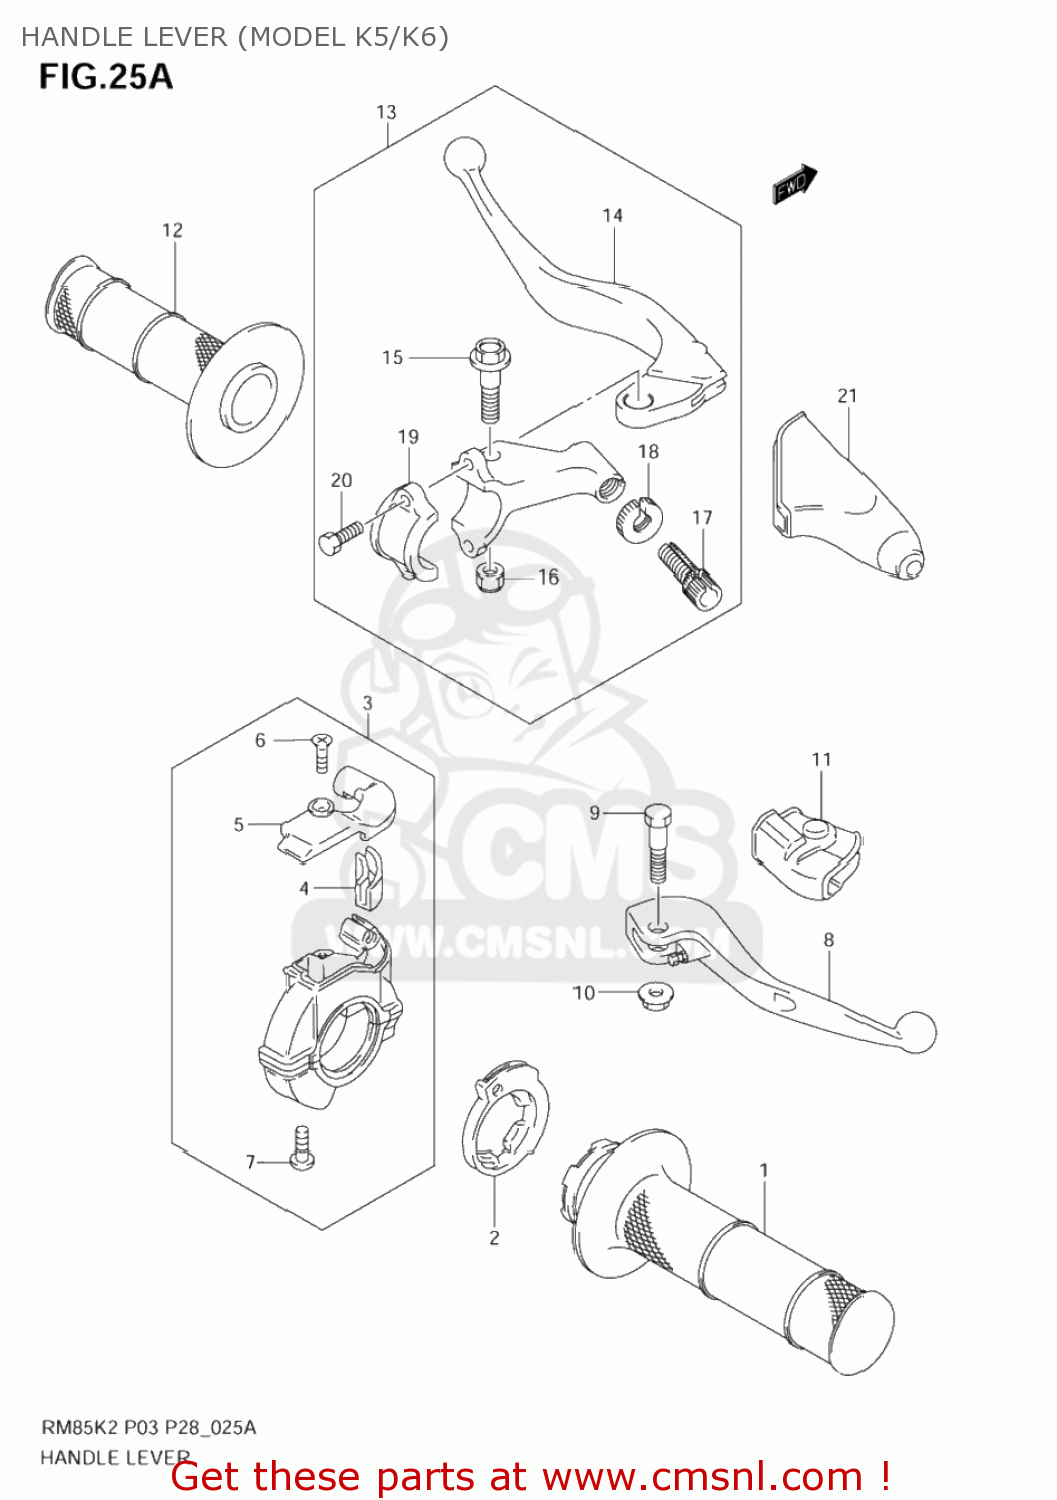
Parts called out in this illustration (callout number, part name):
1	GRIP,THROTTLE
2	ROTOR,THROTTLE GRIP
3	CASE ASSY,THROTTLE
4	GUIDE PIECE,THROTTLE
5	COVER,THROTTLE CASE
6	SCREW,UPPER
7	SCREW
8	LEVER ASSY,BRAKE
9	BOLT,BRAKE LEVER
10	NUT
11	COVER,BRAKE LEVER
12	GRIP,L
13	LEVER ASSY,CLUTCH
14	LEVER,CLUTCH
15	BOLT,LEVER
16	NUT 6MM
17	ADJUSTER,WIRE
18	NUT,LOCK
19	BRACKET,CLUTCH LEVER HOLDER
20	BOLT
21	COVER,CLUTCH LEVER
